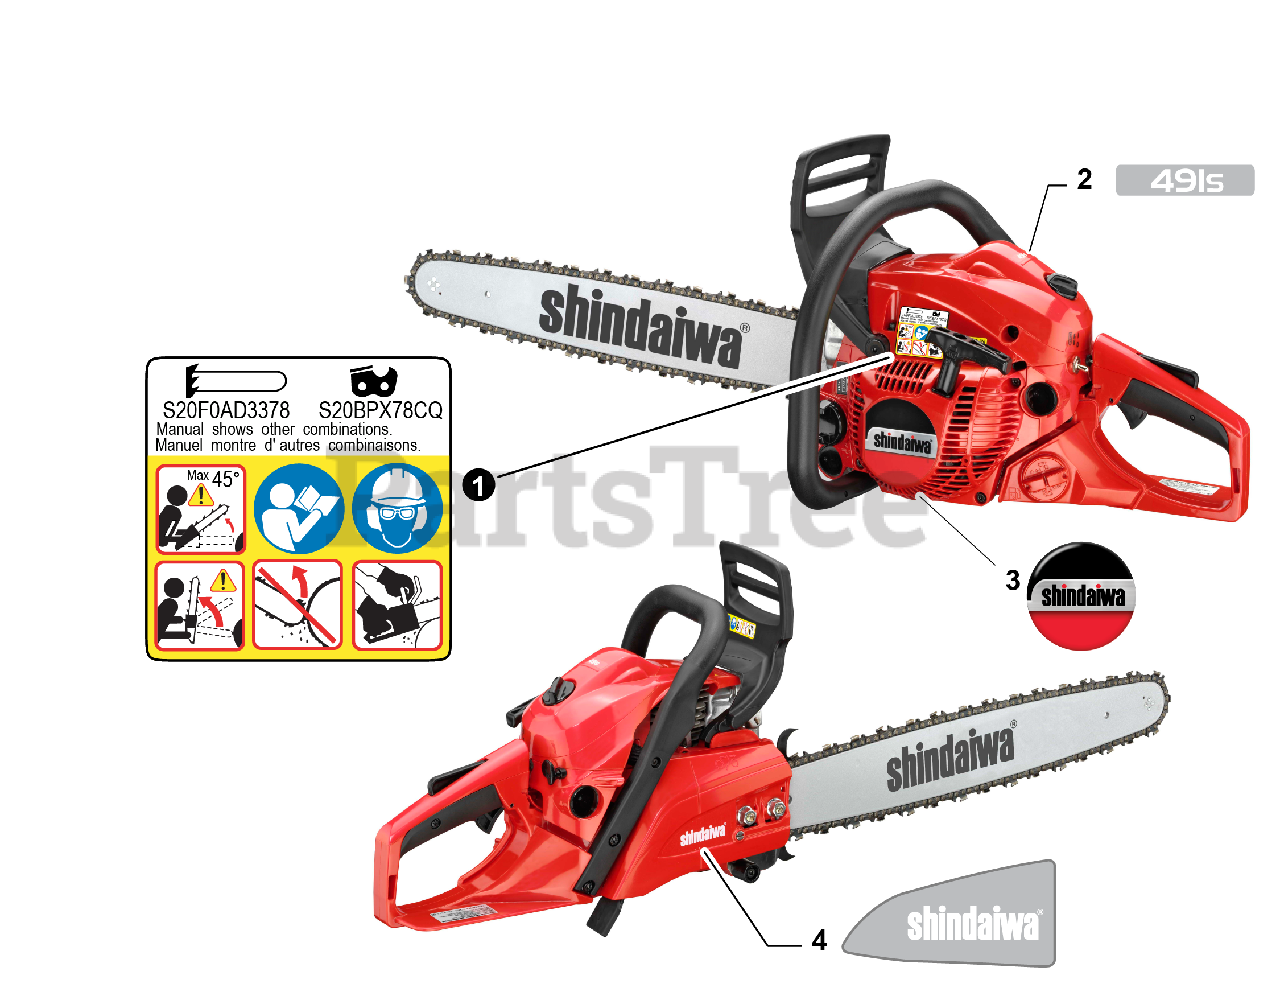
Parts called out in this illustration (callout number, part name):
1	LABEL, CAUTION
2	LABEL - MODEL 491S
3	LABEL, STARTER - SHINDAIWA
4	LABEL - SHINDAIWA
